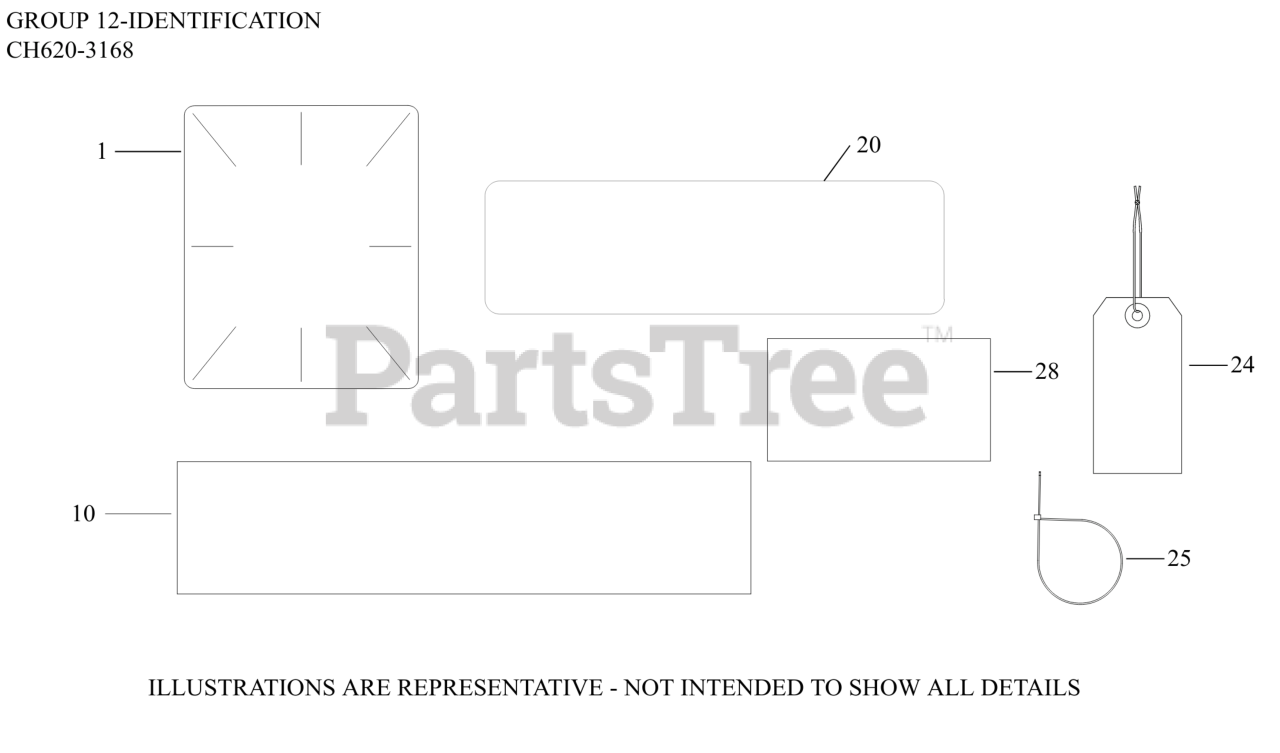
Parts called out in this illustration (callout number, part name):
1	LABEL, CLEAR LAMINATION
10	DECAL, STOPPING INSTRUCTION
20	DECAL LPAC, 19 HP/674cc/CV-CH620
24	TAG, HANG (OIL SENTRY)
28	DECAL, USA
